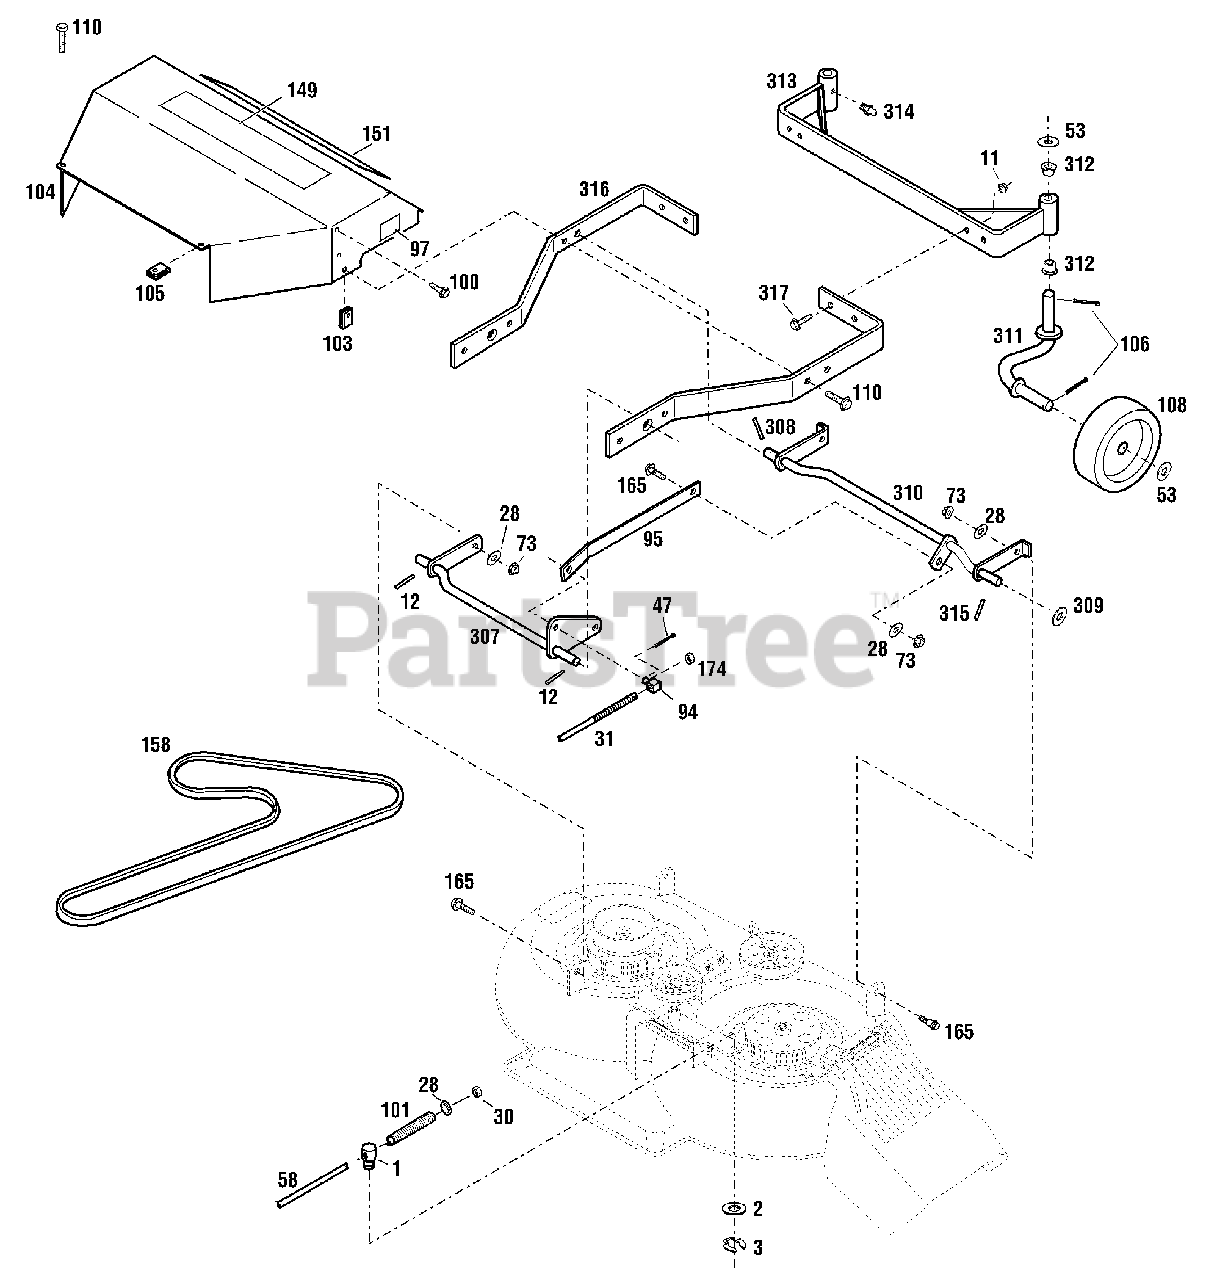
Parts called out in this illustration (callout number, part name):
3	Clip Ring
11	Flange Locknut, 3/8-16
28	Flat Washer, 3/8
30	Locknut, 3/8-16
31	Lift Crank
47	Cotter Pin
53	Special Washer
58	Lower Blade Rod
73	Flange Locknut, 3/8-16
94	Pivot Block
95	Leveler Bar
97	Cutting Height Decal
100	Tap Screw, #8 x 3/8
101	Compression Spring
103	Speed Nut, 5/16-18
104	Belt Guard
105	Speed Nut, 5/16-18
106	Cotter Pin
108	Gage Wheel
110	Flange Lock Screw, 5/16 x 3/4
149	Logo Decal
151	33" Combination Deck Decal
165	Shoulder Bolt
174	Toplock Nut
307	Rear Lift Assembly
308	Roll Pin, 1/4 x 1
309	Flat Washer, 5/8
310	Front Lift Assembly
311	Spindle Assembly
312	Flange Bearing
313	Gage Support
314	Grease Fitting
315	Drive Pin, 1/4 x 3
316	Mower Support
317	Whizlock Screw, 3/8-16 x 1
